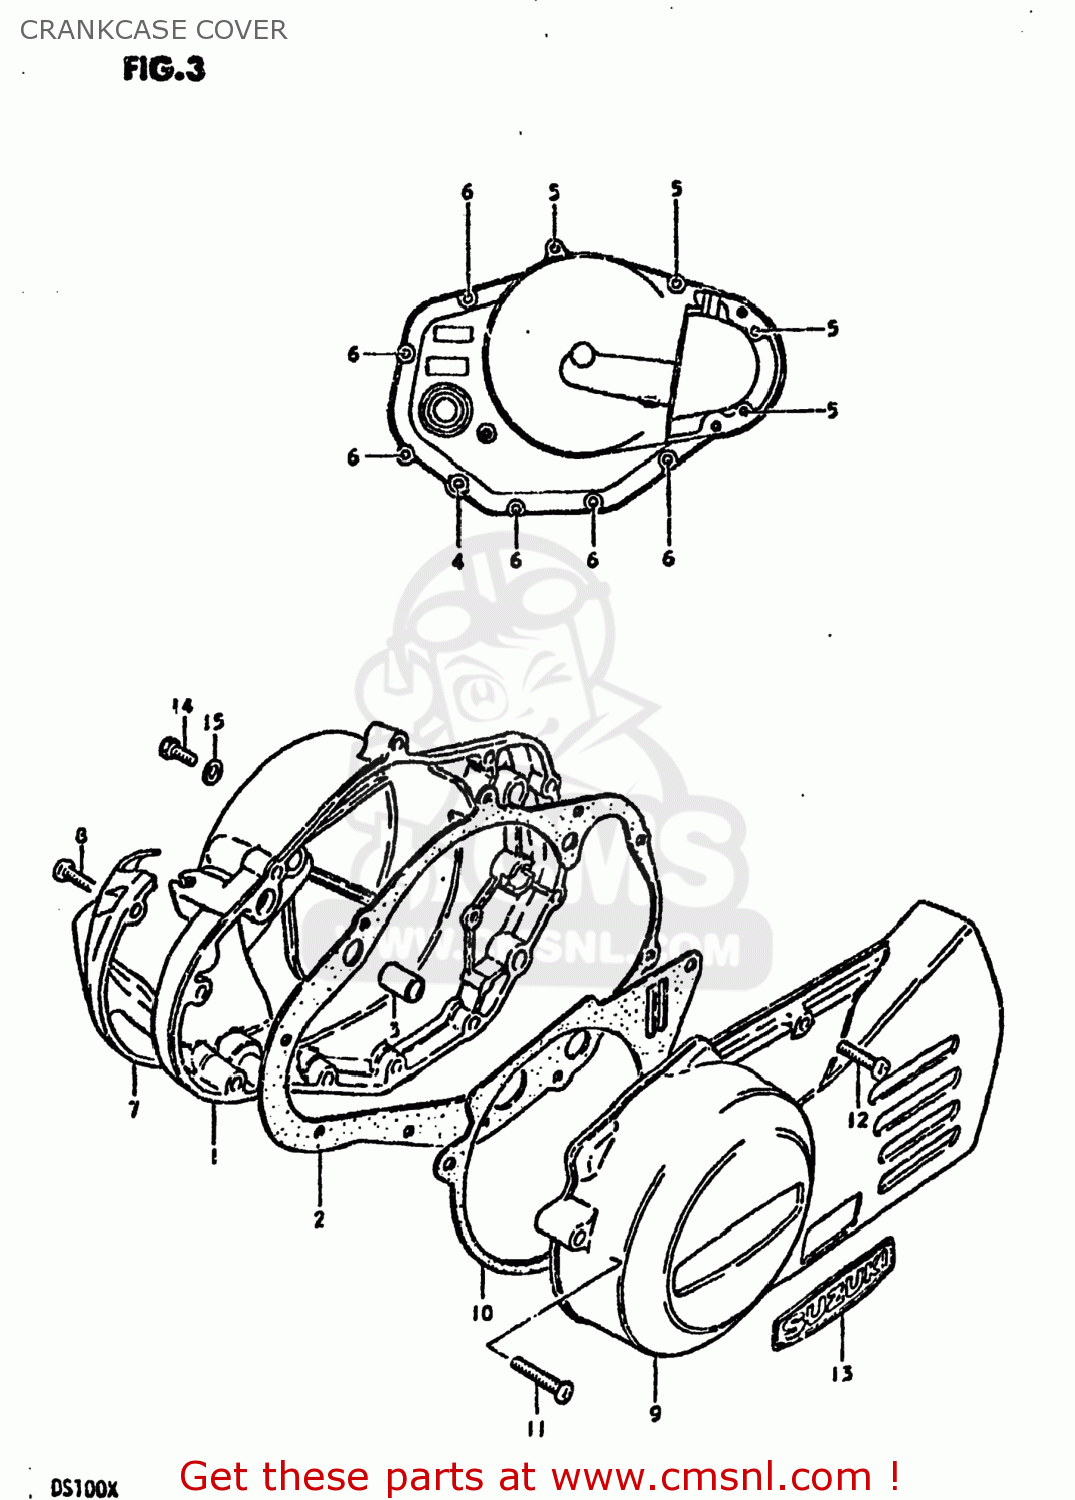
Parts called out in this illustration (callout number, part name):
1	COVER,CLUTCH
2	GASKET,CLUTCH COVER (MCA)
3	PIN
4	SCREW (6X45)
5	SCREW 6X30
6	SCREW
7	COVER,CLUTCH RELEASE ARM
8	SCREW
9	COVER,MAGNETO
10	GASKET,MAGNETO COVER (NAS)
11	SCREW 6X30
12	SCREW
13	EMBLEM,GENERATOR COVER
14	SCREW(6X10)
15	GASKET(6.2X11X1) (NAS)
